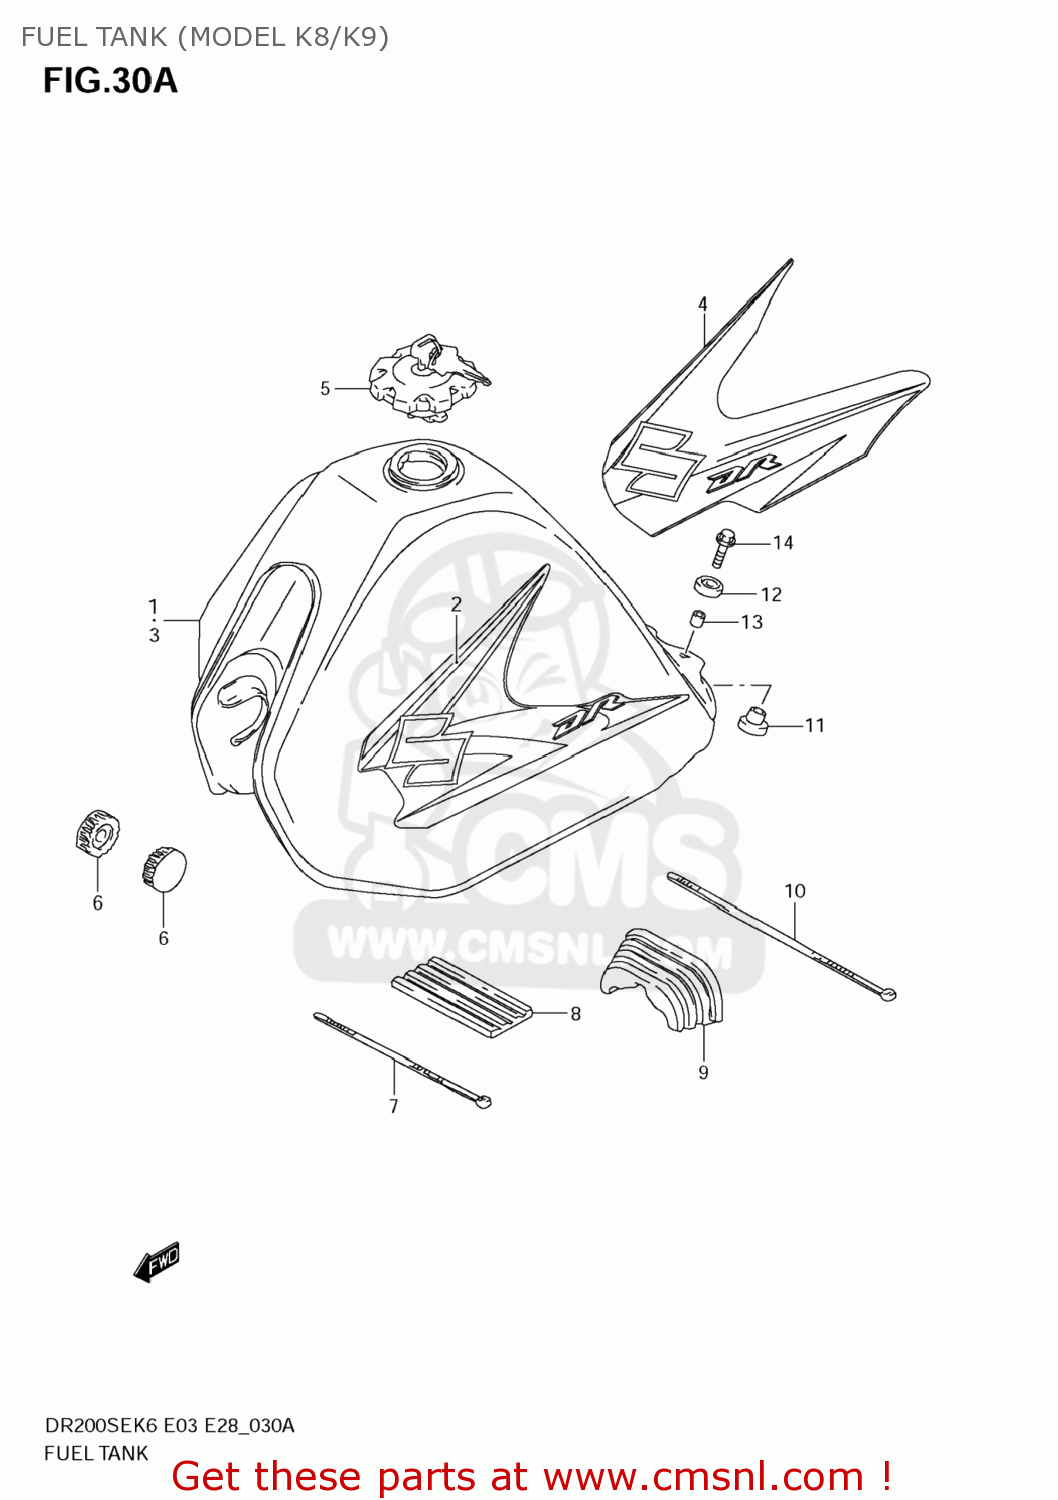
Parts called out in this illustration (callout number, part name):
1	TANK ASSY,FUEL
2	TAPE SET,FUEL TANK
3	TANK ASSY,FUEL(BLACK)
4	TAPE SET,FUEL TANK
5	CAP SET,FUEL TANK
6	CUSHION
7	CLAMP(L:250)
8	CUSHION,FUEL TANK UPR FR
9	CUSHION,FUEL TANK RR
10	CLAMP(L:300)
11	CUSHION
12	CUSHION
13	SPACER(6.5X9X18)
14	BOLT
